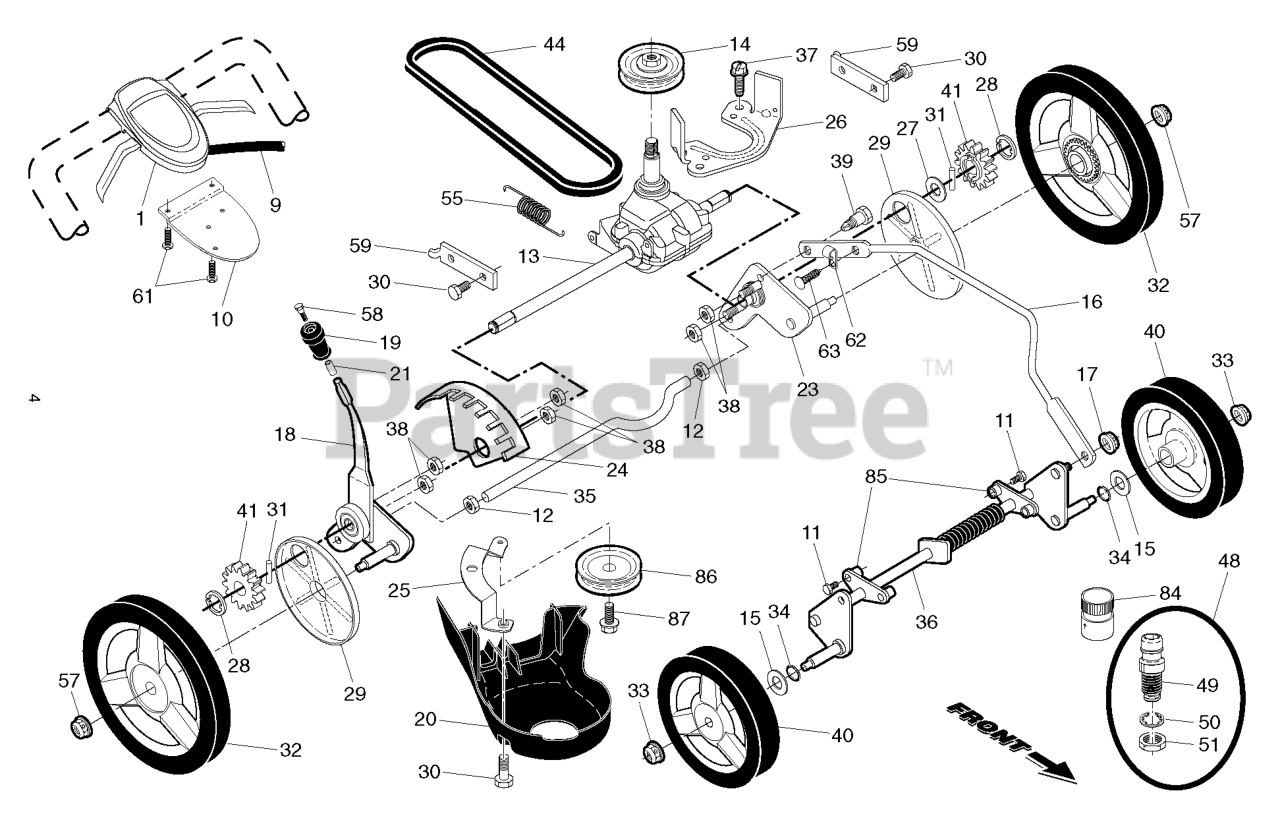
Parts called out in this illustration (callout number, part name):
1	CONTROL.AW2.22+RG.BS.GEN.BK/BK
9	CABLE.DRIVE.RWD.WALK.
10	BRACKET.DRIVE.CONTR.GEN2.BLACK
11	SCREW.HX.13X.750
12	NUT.HEX.1/2-20
13	TRANSMISSION.22+AWD.WALK.MOWER
14	PULLEY.DRIVE.SM.AWD/RWD
15	WASHER.FLAT.1/2
16	ROD.CONNECTING.RGD.22+.HW.BLAC
17	NUT.LOCK.5/16-18
18	KIT.SEL.ASM.22+RG.11"HW.BLKNB
19	KNOB.SEL.SPRING.22+.SP.RIB.BLK
20	COVER.REAR.DRIVE.22+2013
21	SCREW.PLASTIC.ANCHOR.5/16
23	ADJUSTER.ARM.ASM.LT.SP.HW.BZP
24	BRACKET.WHL.ADJ.9.POS.W/PAD
25	BRACKET.DRIVE.COVER.RGD.
26	BRACKET.TRANS.BELT.KEEPER.BZP
27	WASHER
28	E-RING 7/16 RE
29	COVER.DUST.WHEEL.RGD.HW.NEW
30	BOLT.5/16HEX.WHS.HD
31	PAWL, DRIVE
32	RP_WHEEL.11.RAD3.460.BB2.NEW.H
33	NUT.HEX.FLANGE.3/8-16.LO(3 2)
34	O-RING..070X.487.NEOPRENE
35	AXLE.REAR.RGD
36	AXLE.ASM.FRT.RGD.BZP
38	NUT.HEX.FLANGE.1/4
39	SHOULDER BOLT SEMI GIMLET PT.
40	WHEEL & TIRES ASSY, FRONT
41	PINION.12.TEETH.RGD.22+HW
44	BELT.DRIVE.RWD+.SS.ZINC DUST
48	KIT.WASH-OUT.PORT
49	FITTING, HOSE, WATER WASHOUT
50	WASHER.LOCK.INTERNAL.TOOTH
51	LOCKNUT.HEX.WITH.O-RING
55	SPRING.RETURN.AUTO.
57	NUT.HEX.FLANGE.3/8-16.LOCKNUT
58	SCREW.12-14X1.500
59	BRACKET.SUPPORT.22+RWGD.BZP
61	SCREW, PHILLIPS HEAD 10 X 5/8
62	CLIP.CABLE.BLK
63	FASTENER.PUSH.O.250X0.783
84	COUPLING.QUICK CONNECT
85	BRACKET.FRT.AXLE.SUPPORT
86	PULLEY.RWD.IDLER.DBL SEAL
